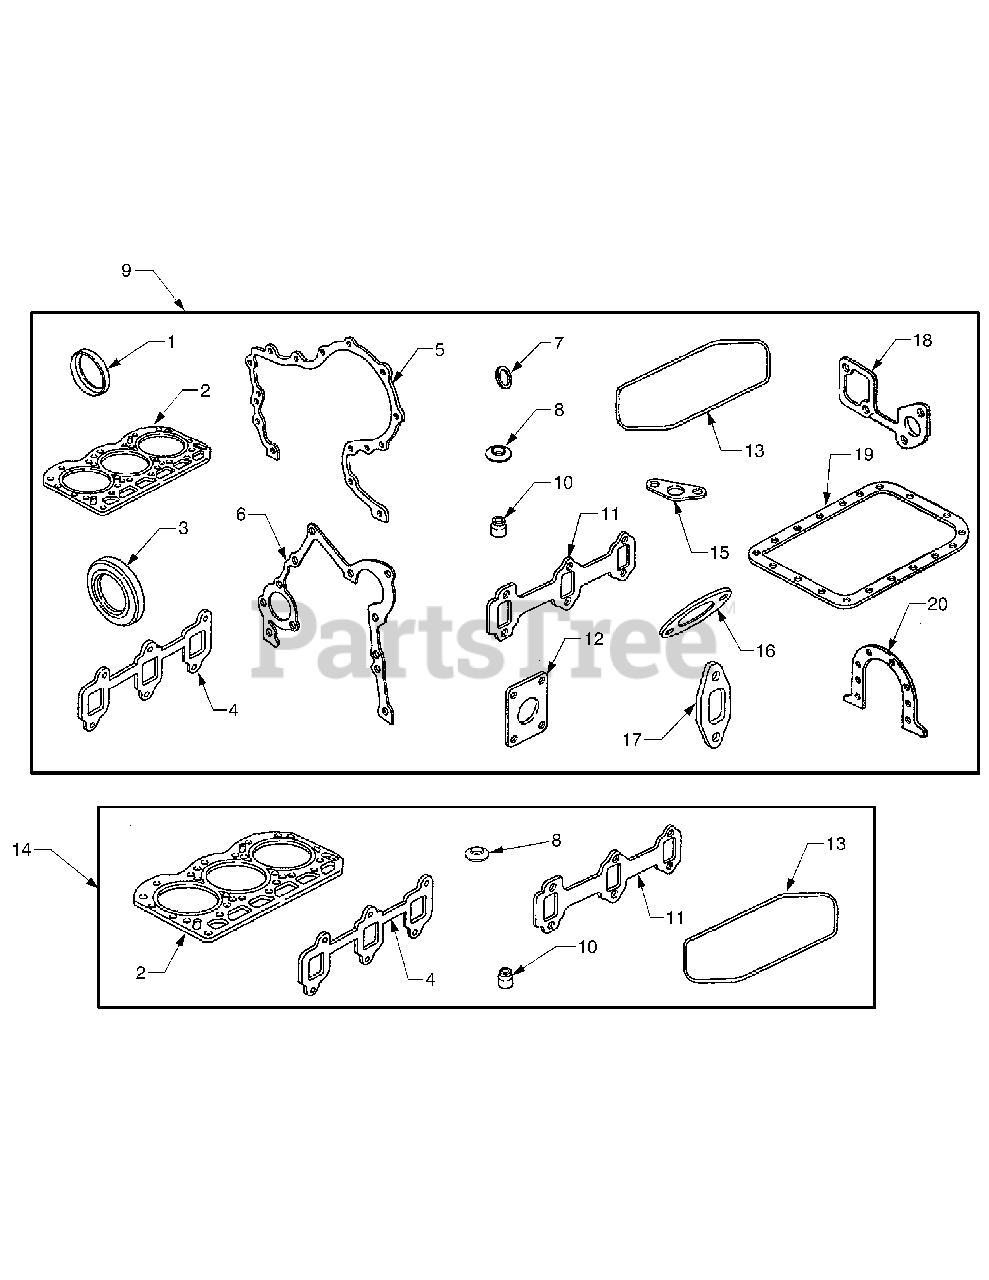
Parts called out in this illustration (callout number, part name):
2	Gasket, Cylinder Head
3	Seal, Oil
4	Gasket, Intake
5	Gasket, Gear Cover
6	Gasket, Gear Cover
7	Washer, Sealing
8	Washer, Sealing
9	Gasket Set - Engine
10	Seal, Valve
11	Gasket, Exhaust
12	Gasket, Exhaust
13	Gasket, Rocker Cover
14	Gasket Set - Valve
15	Gasket, Oil Pump Screen
16	Gasket, Outlet
17	Gasket, Inlet Housing
18	Gasket, Water Pump
19	Gasket, Oil Pan
20	Gasket, Retainer
